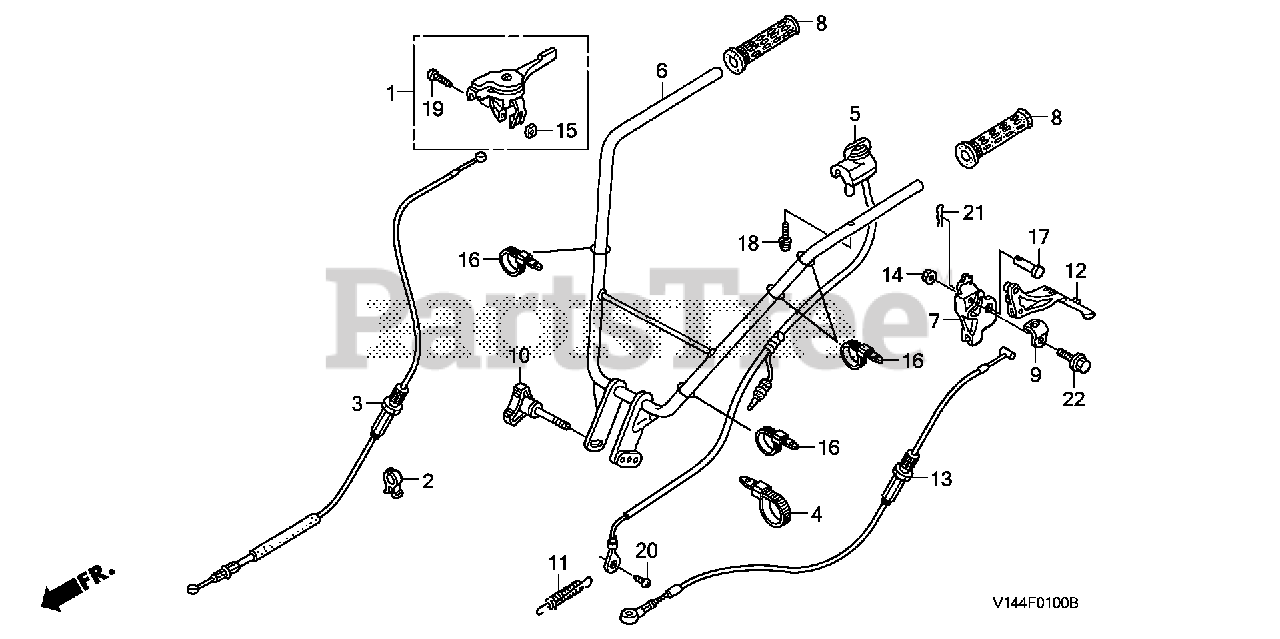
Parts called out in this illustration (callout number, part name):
1	LEVER ASSY., THROTTLE
2	CLIP, THROTTLE
3	CABLE, THROTTLE
4	BAND B1, WIRE
5	SWITCH ASSY., ENGINE STOP
6	PIPE, HANDLE
7	BRACKET, HANDLE
8	GRIP, L. HANDLE
9	BAND, HANDLE BRACKET
10	GRIP, HANDLE JOINT
11	SPRING, CLUTCH
12	LEVER, CLUTCH
13	CABLE, CLUTCH
14	NUT, SPECIAL (6MM)
15	NUT, SQUARE (5MM)
16	BAND, CABLE (120MM) (BLACK)
17	PIN, SIDE CLUTCH LEVER
18	SCREW-WASHER (3X12)
19	SCREW, PAN (5X20)
20	SCREW, TAPPING (5X8)
20	SCREW, TAPPING (5X10)
21	PIN, LOCK (8MM)
22	BOLT, FLANGE (6X25)
